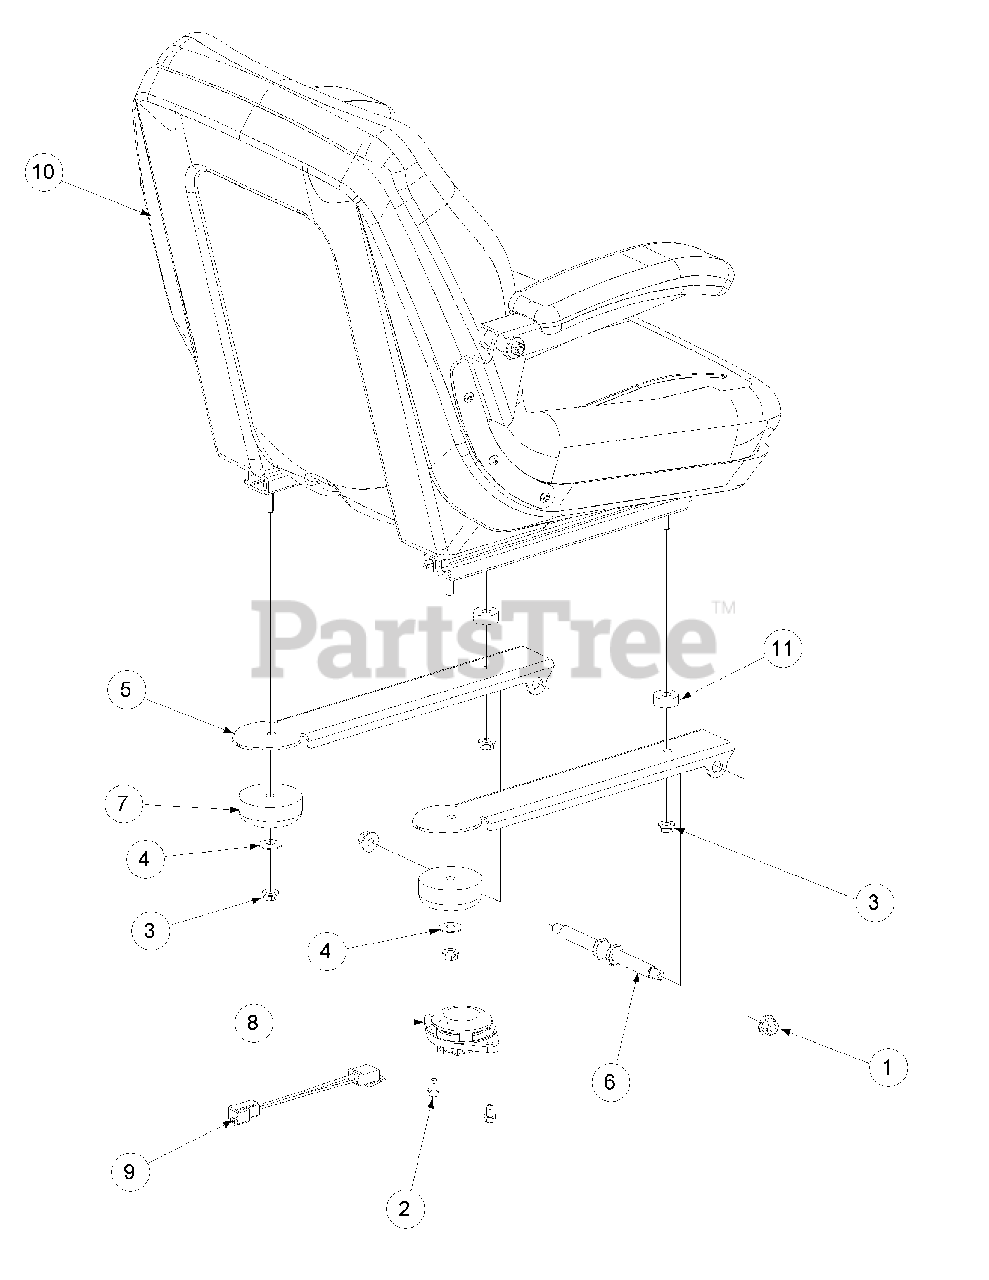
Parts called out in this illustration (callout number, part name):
1	Nut, Hex 3/8-16 Flange Lock
2	Screw, TT, 1/4-20, 0.5, Hex Index Washer
3	Lock Nut, Hex Flange, 5/16-18
4	Washer
5	Mounting Bracket, Seat
6	Shoulder Screw, .50x2.345, 3/8-16
7	Grommet, 2.5 OD x 1.0 Long
8	Seat Switch, NC
9	Wiring Adaptor
10	Adjustable Seat, Black w/Armrest
10	Armrest Kit
10	Screw, Button Head 1/4-20 x .50
11	Spacer, 0.406 ID x 1.00 OD x .38
